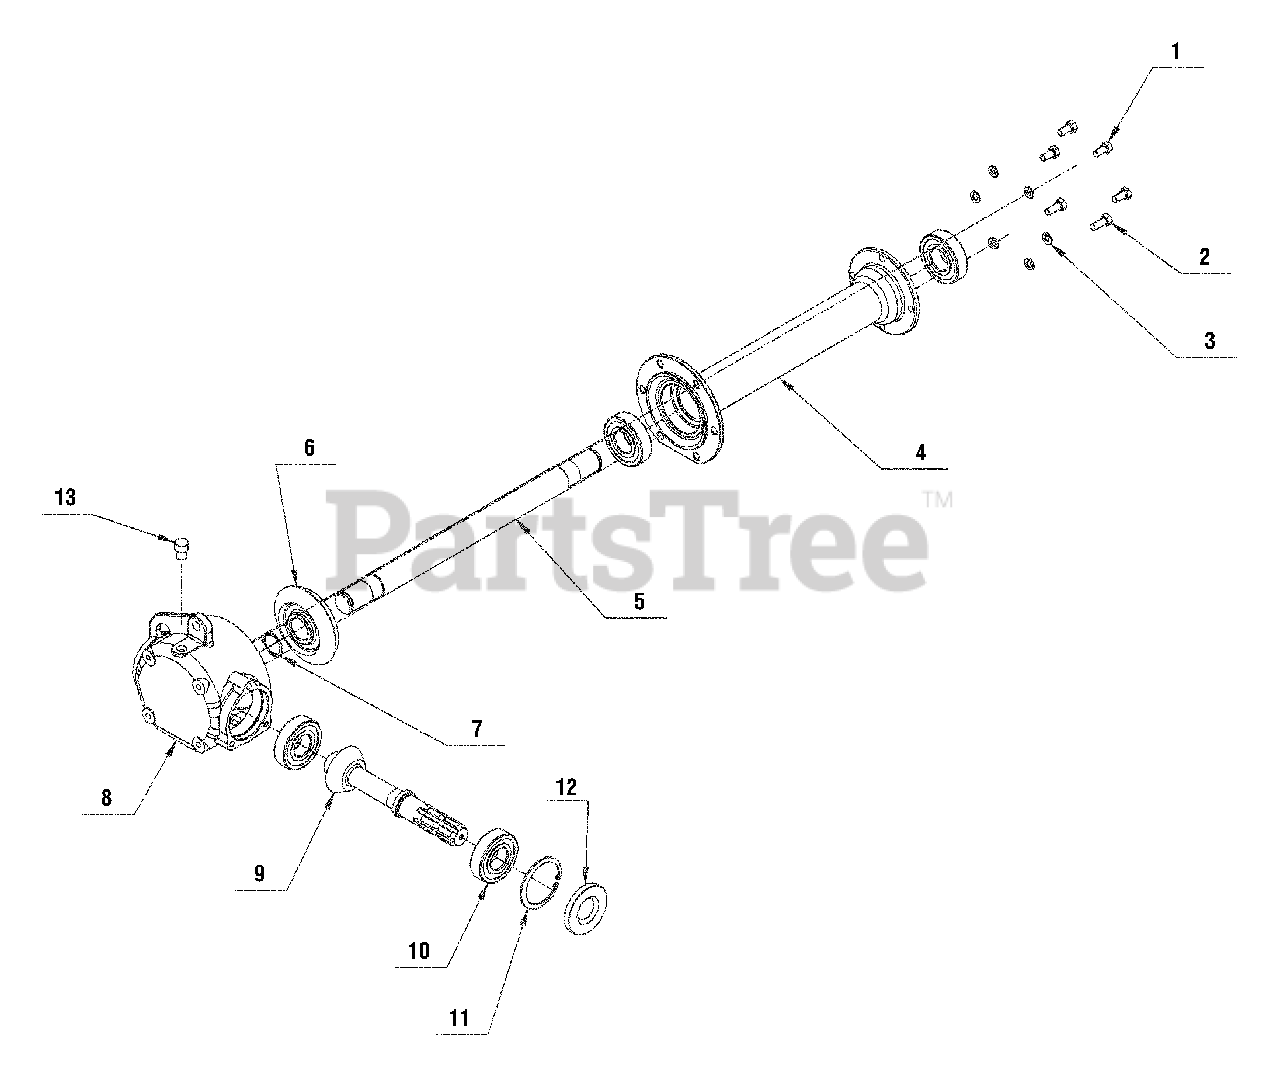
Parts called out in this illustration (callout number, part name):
4	Tube, Output Shaft
5	Shaft, Output
6	Gear, Miter
7	Snap Ring
8	Housing, Gearbox
9	Shaft, Input
10	Bearing, Gearbox
12	Spacer, 35 x 80 x 10
